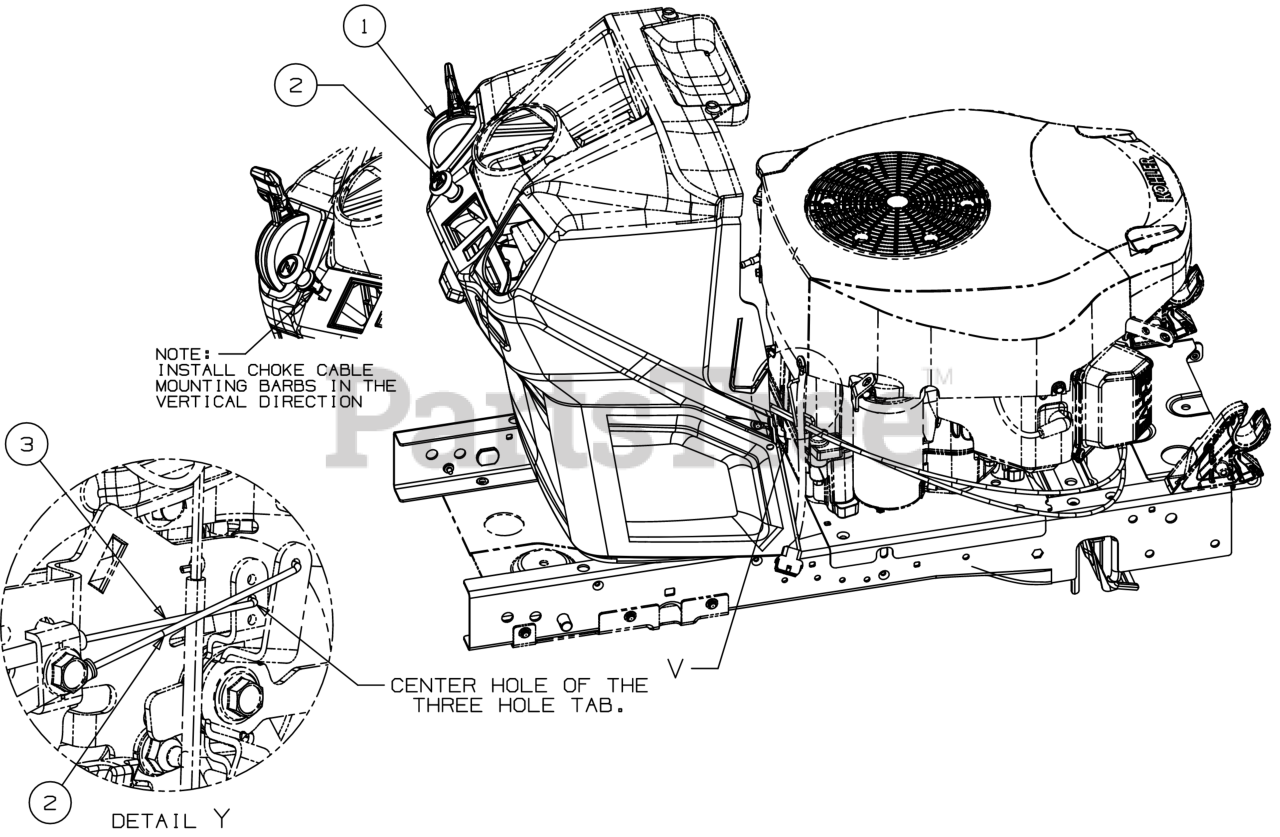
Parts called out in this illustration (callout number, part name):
1	THROTTLE CABLE 43.5"
2	CHOKE CABLE 46.5" x 1.5
3	CABLE GUIDE WIRE
